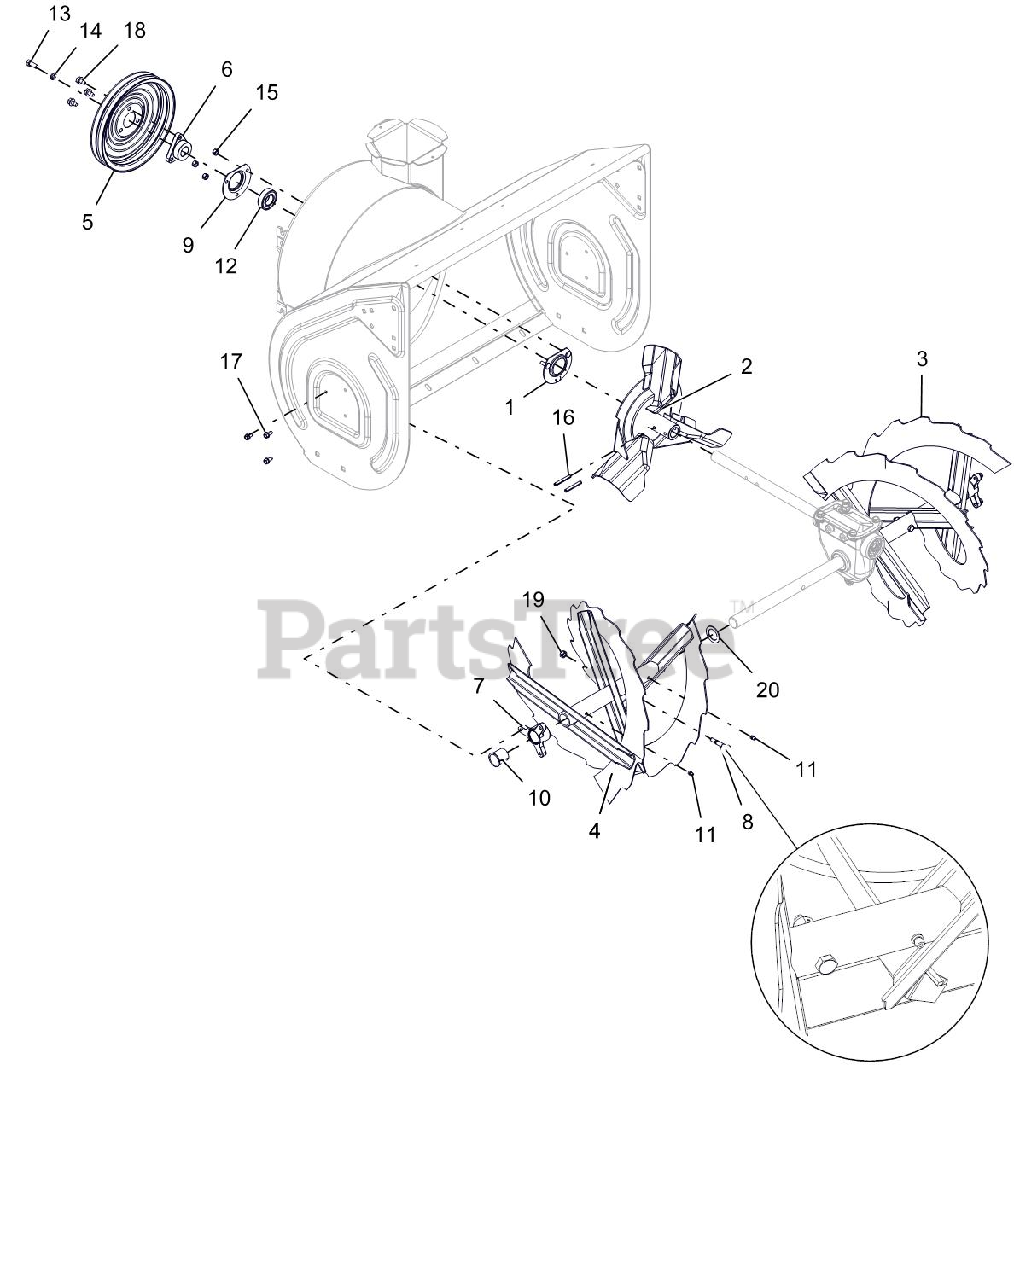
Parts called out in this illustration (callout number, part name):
1	BEARING FLANGE
2	IMPELLER, 3 BLADE-14"
3	RAKE, LH-28"(1 ID X 15.75 OD)
4	RAKE, RH-28"(1 ID X 15.75 OD)
5	PULLEY, SPIN FORM DUAL GROOVE
6	PULLEY HUB, D-BORE .87 PRO
7	BUSHING, RAKE SHAFT 1"
8	SHEAR BOLT SERVICE ASSEMBLY
9	BEARING FLANGE
10	BSHG-FLG SPLIT NYLINER 1.0" HP
11	ZERK,FITTING .25X.125 DRIVE IN
12	BRG-BALL .876X1.75X.50 RSTFP
13	BLT-HEX .31-24X.75 YWZC GR5
14	WSHR-LK .312X.097 HVY YWZC
15	@NUT-LK-CTR .25-20 YWZC
16	PIN-ROLL .250X1.75
17	SCR-TAP .25-20X.50 HWH TR YWZ
18	@SCR-TAP .31-18X.50 HWH TR YWZ
19	@NUT-LK-CTR .31-18 YWZC
20	WSHR-FL-STL 1.010X1.505X.062YZ
